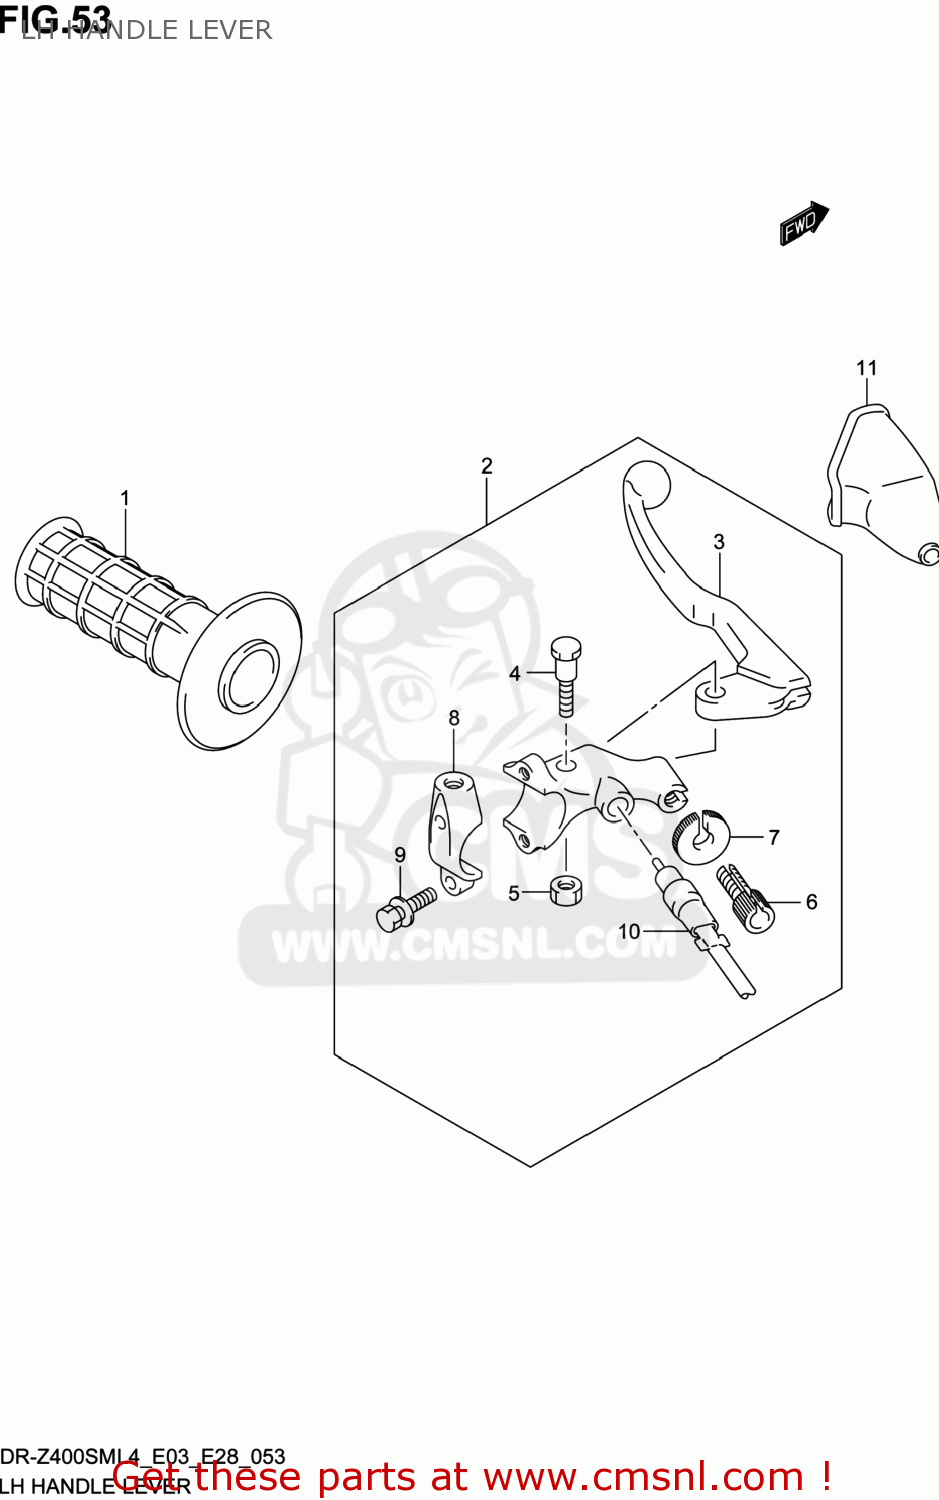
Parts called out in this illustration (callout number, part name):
1	GRIP,L
2	LEVER ASSY,CLUTCH
3	LEVER,CLUTCH
4	BOLT,LEVER PIVOT
5	NUT
6	ADJUSTER,WIRE
7	NUT,LOCK
8	BRACKET,HOLDER
9	BOLT,BRACKET
10	SWITCH ASSY,CLUTCH
11	COVER,CLUTCH CABLE DUST
